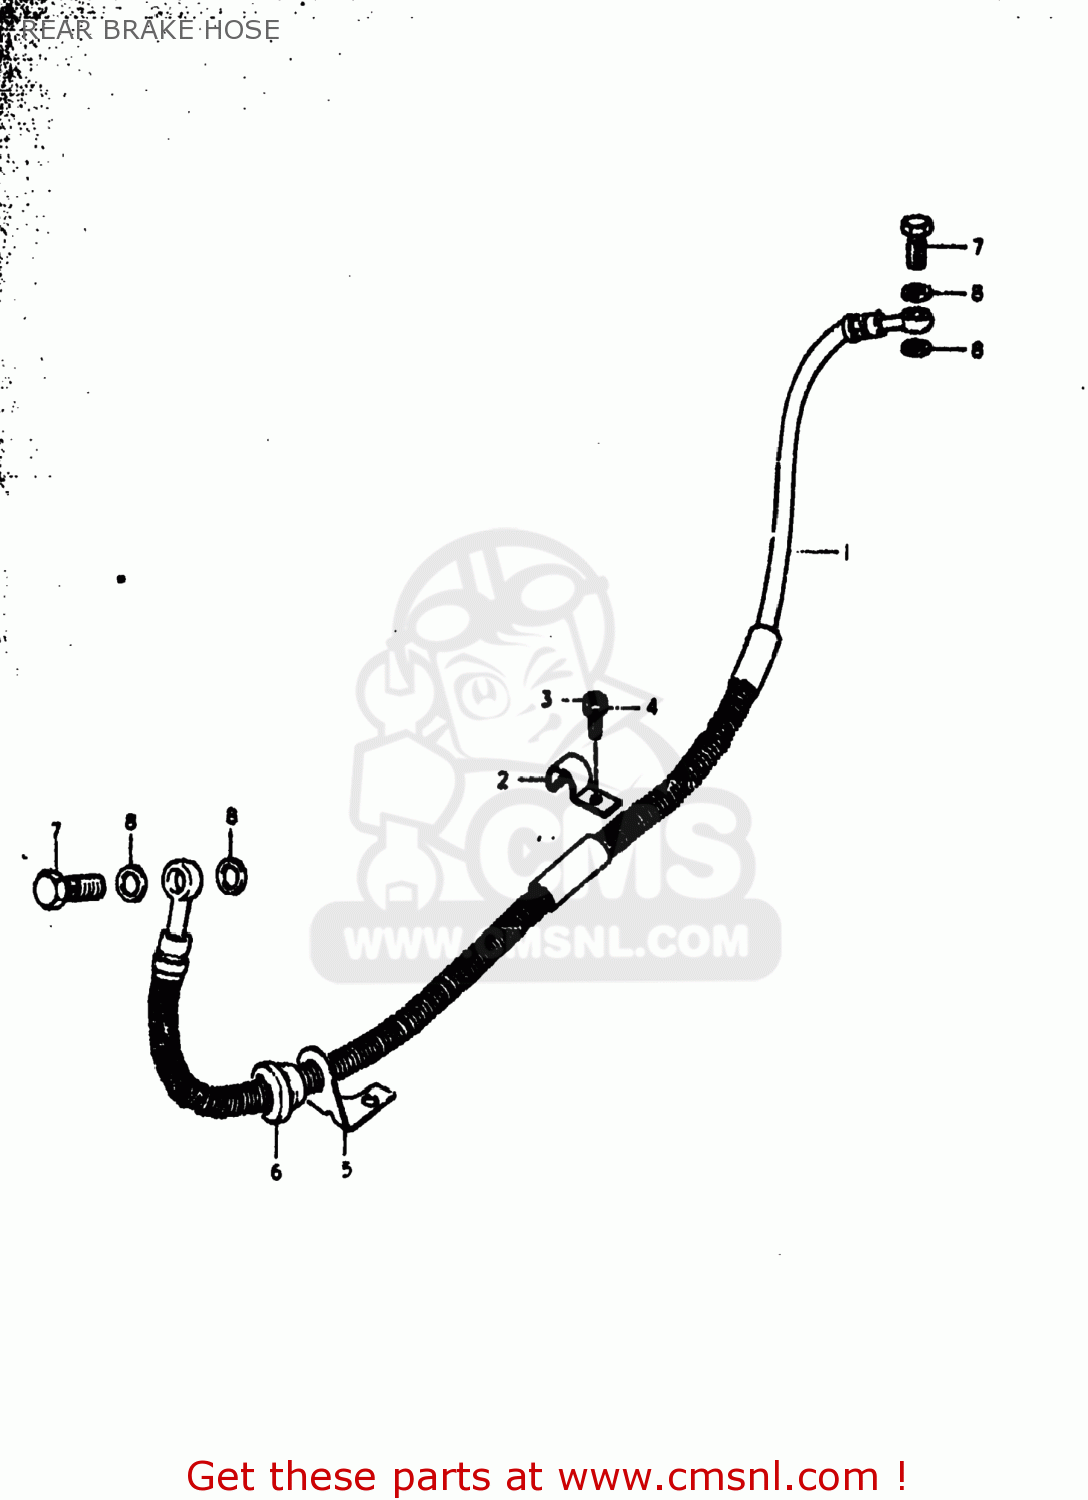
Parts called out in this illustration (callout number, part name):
1	HOSE,REAR BRAKE
2	CLAMP,REAR BRAKE HOSE
3	SCREW(6X8)
4	LOCK WASHER
5	GUIDE,BRAKE HOSE
6	GROMMET,BRAKE HOSE GUIDE
7	BOLT UNION
8	WASHER
